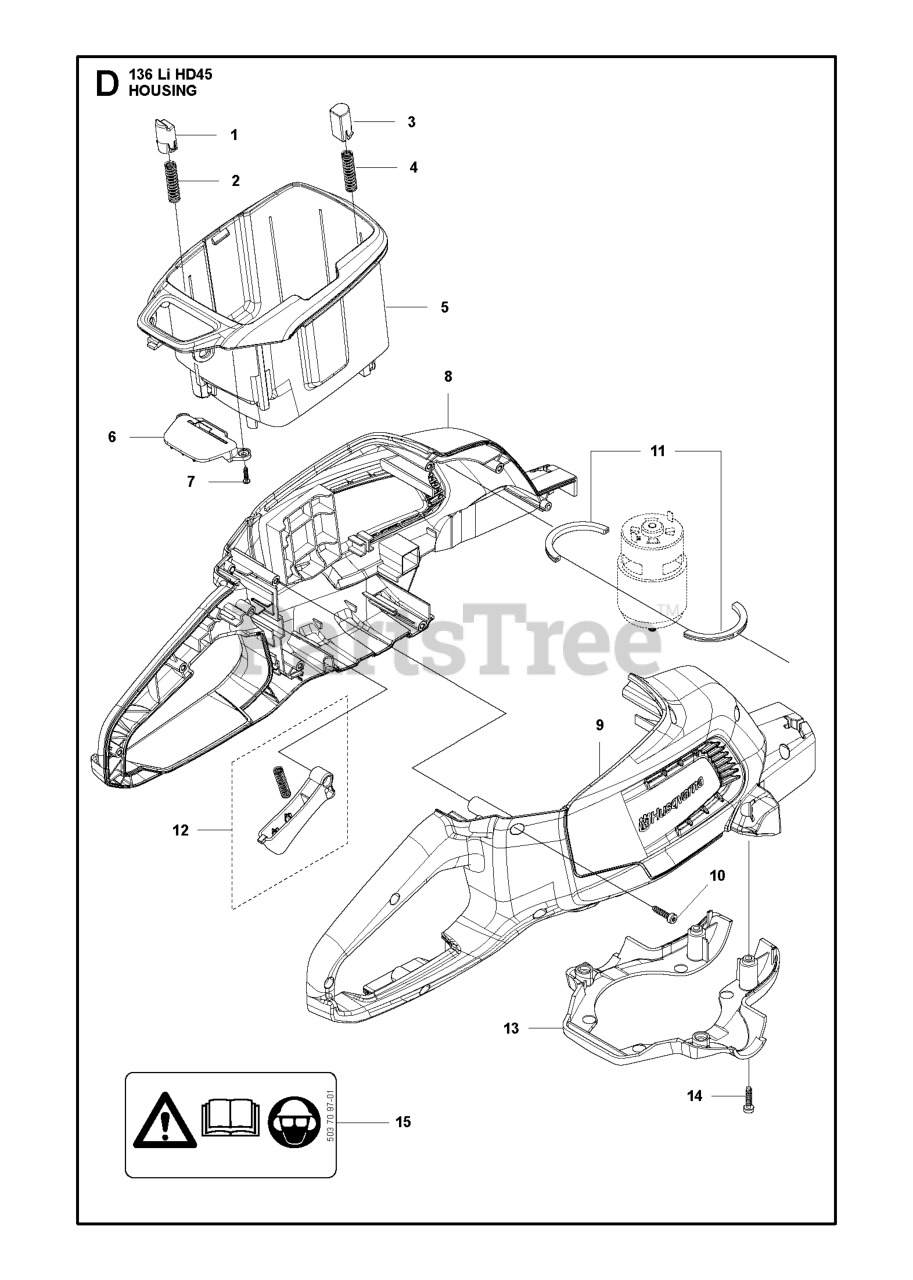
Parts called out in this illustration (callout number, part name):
1	PUSH BUTTON
2	SPRING PUSH BUTTON
3	PUSH BUTTON FRONT
4	SPRING PUSH BUTTON
5	BATTERY BOX
6	BRACKET KEYPAD
7	SCREW ST3X8
8	HOUSING RIGHT
10	SCREW ST4X16
13	COVER BOTTOM
14	SCREW ST4X16
